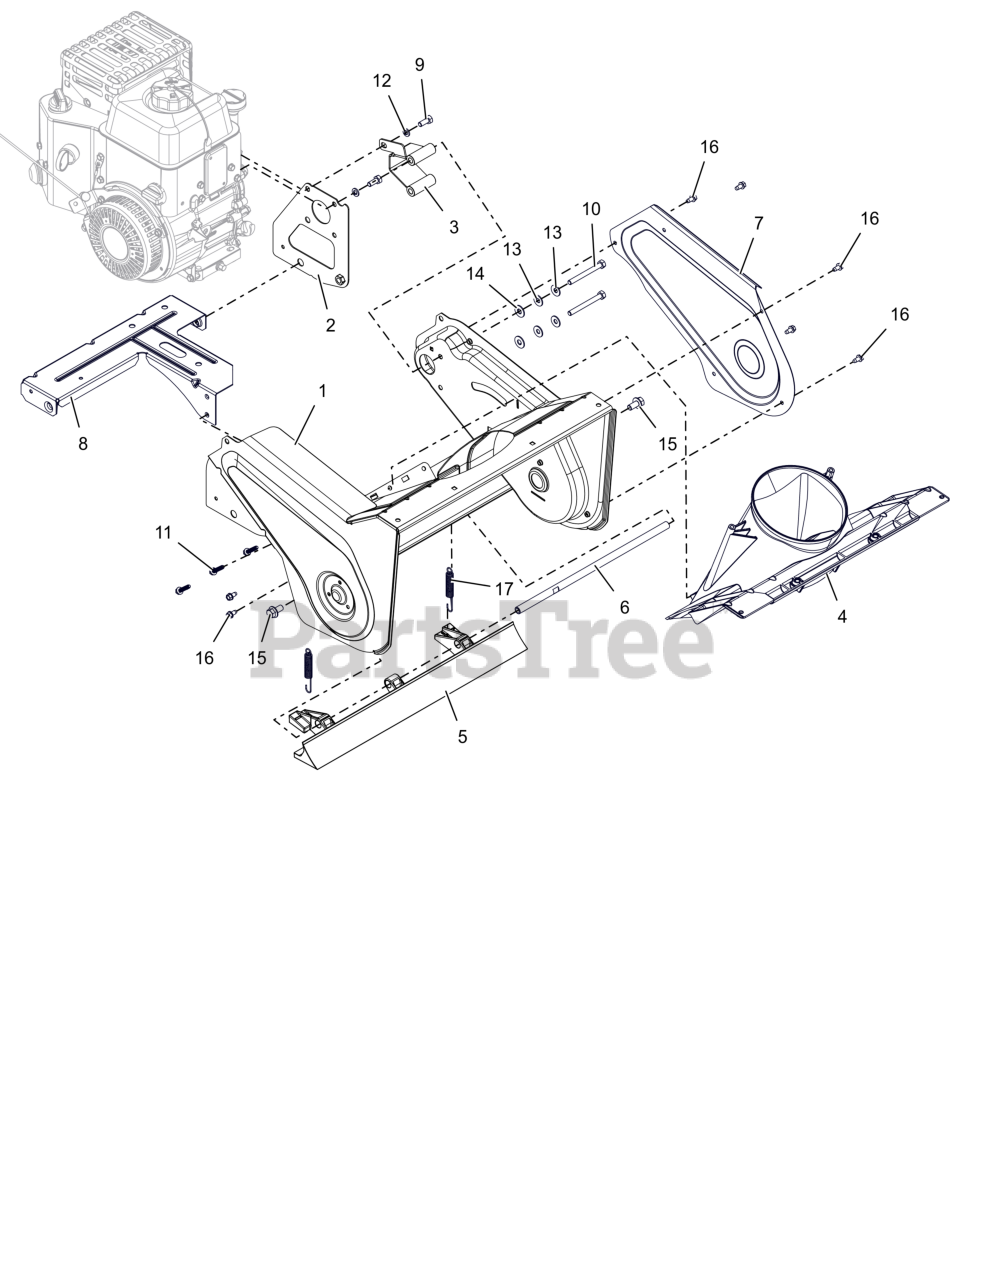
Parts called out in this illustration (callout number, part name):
1	WLDMT, HOUSING - CSS
2	FRAME, DRIVE BRACKET - WLMT
3	SPACER- FRAME PTO SPACER/GUARD
4	NECK, DISCHARGE
5	BLADE, SCRAPER - PIVOTING
6	ROD, PIVOT - SCRAPER
7	COVER, BELT DRIVE - HOUSING
8	FRAME, ENGINE T-PLATE
9	BLT, HEX .31-24X.750 G5ZCCEP30
10	BLT, HEX .31-24X3.00 G5 ZCC
11	SCR,PLASTITE .25-10X1.25 ZCC
12	WSHR,LK-REG .312X.078 ZCC
13	WSHR,BLVL-.322X.813X.063
14	WSHR, HDND .375X.875X.064 ZCC
16	SCR-TAP .25-20X.50 HWH ZCC
17	SPRING,EXT-.063 X .500 X 3.500
